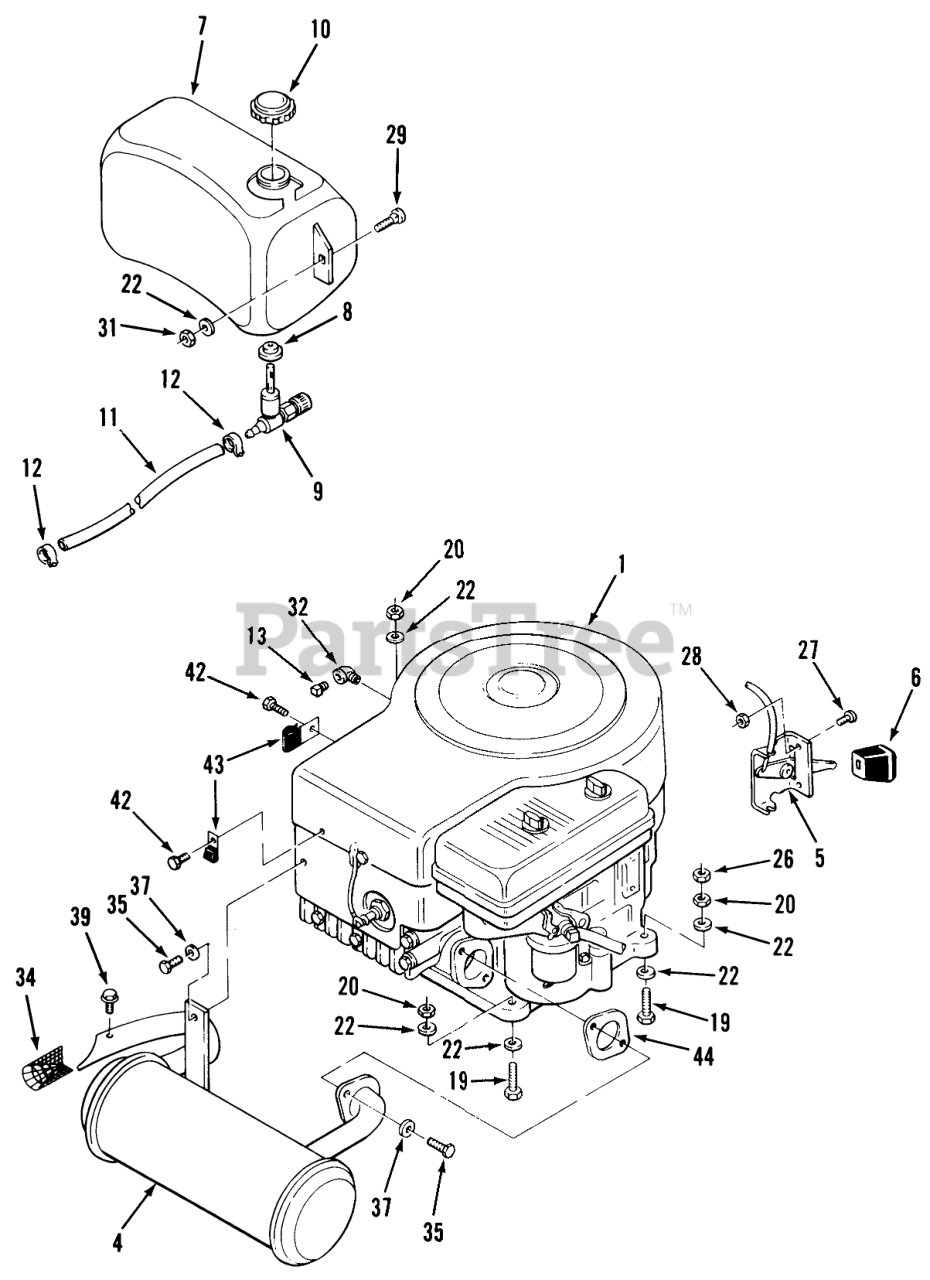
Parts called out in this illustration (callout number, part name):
1	Engine-12HP-B & S Model 281707-0226-01 Model 212-HA
4	EXHAUST-MUFFLER
5	THROTTLE-CONTROL
6	KNOB-CONTROL
7	Fuel Tank Assembly (Incl. Ref. #8 & 9)
8	BUSHING
9	VALVE-FUEL
10	CAP GAS
11	FUEL LINE 19" OF 6554
12	CLAMP-HOSE
13	Plug
19	HHCS
20	Nut
22	WASHER-PLAIN
24	Screw-Cap Hex. Hd.
26	Nut
27	Screw
28	Nut
29	BOLT-CARR
31	NUT-LOCK, NI
32	STREET ELBOW 45DEGRE
34	Arrester-Spark
35	SHCS 5/16-18X.625
37	WASHER-LOCK
39	BOLT-HEX S.T. #8X1/2
42	HHCS M8X1.25X15
43	J-CLIP
